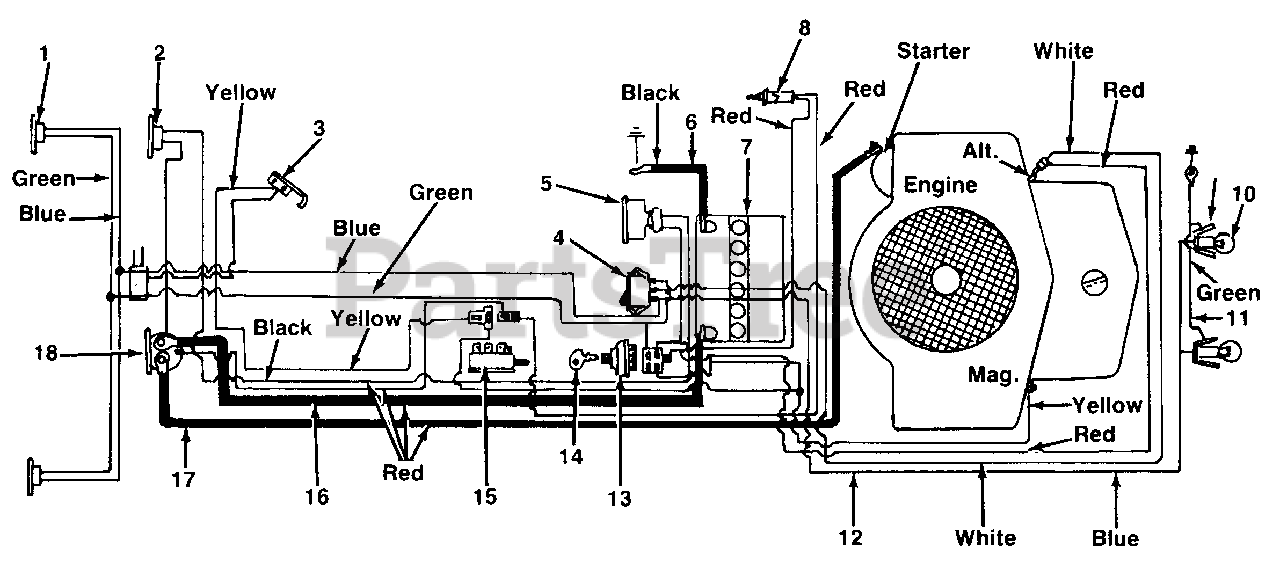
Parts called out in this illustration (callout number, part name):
1	Taillight
2	Circuit Breaker
3	Switch Spring
4	Headlight Switch
5	Ammeter
6	Electric Wire 14.0" Lg. Black
7	12V Battery
8	Safety Switch
10	Lamp 12V Socket Type
11	Double 14 x 5 Wire Lead
12	Wire Harness
13	Ignition Switch
14	Ignition Key
15	Safety Switch
16	6 Ga. Electric Wire
17	Electric Wire
18	Solenoid
